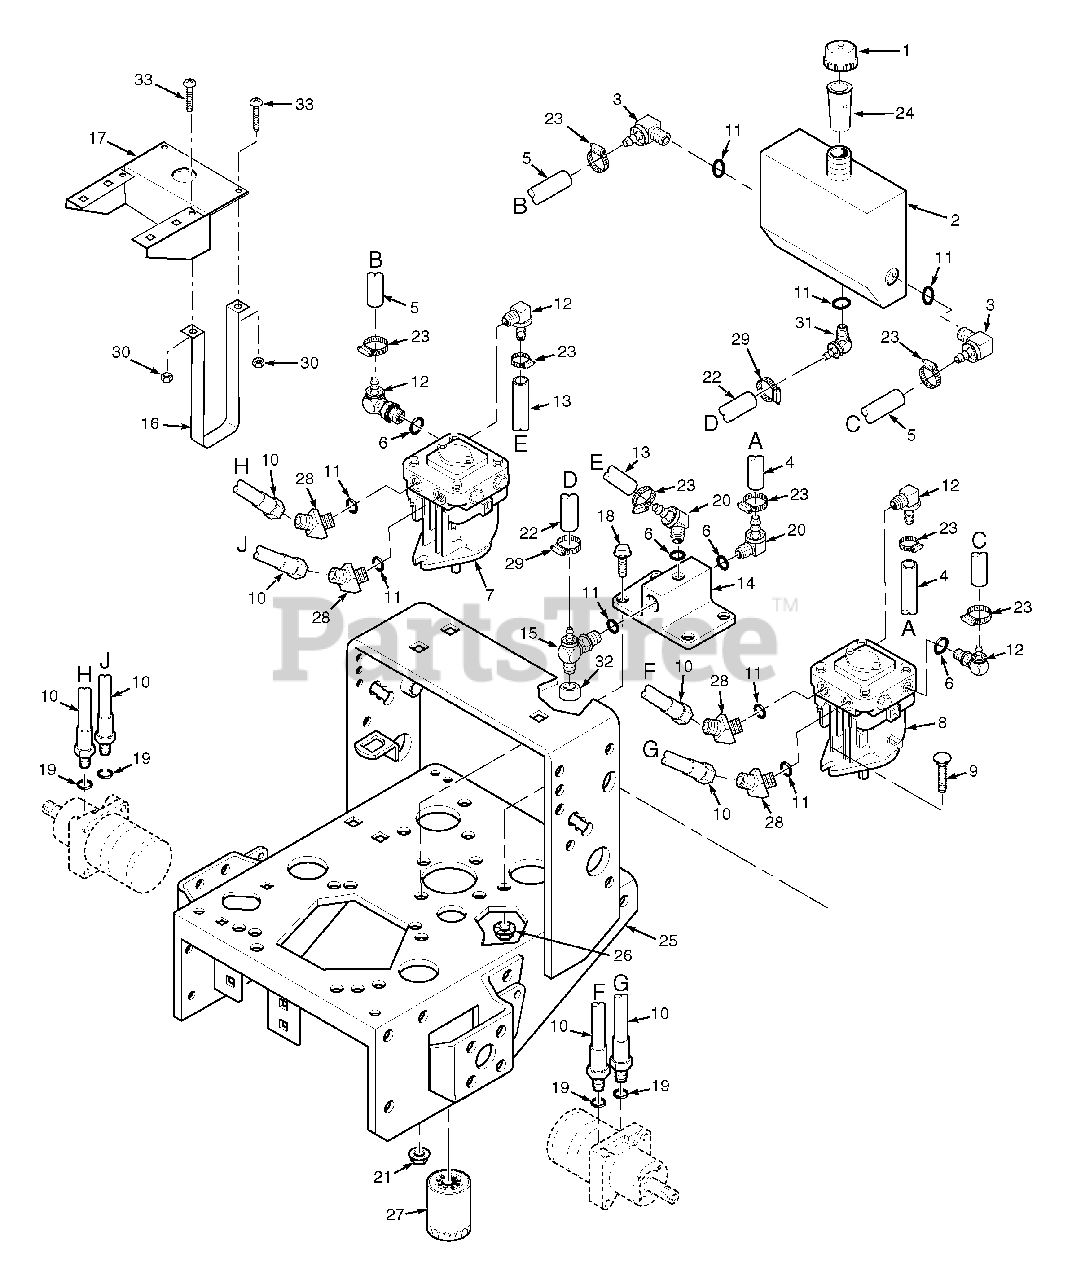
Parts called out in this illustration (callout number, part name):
1	Cap, Oil Reservoir
2	Oil Reservoir (With Fittings)
3	Elbow, 9/16 O-Ring x 3/8 Hose
4	Hose, 3/8" ID - 10-1/4" Long
5	Hose, 3/8" ID - 7" Long
6	O-Ring
7	Pump, PG-1JQQ-DY1X-XXXX (R.H.)
8	Pump, PG-1GQQ-DY1X-XXXX (L.H.)
9	Bolt, Carriage, 3/8-16 x 1.25"
10	Hose, Pump to Wheel Motor
11	O-Ring
12	Elbow, 7/16-20 O-Ring x 3/8 Hose
13	Hose, 3/8" ID - 8-1/4" Long
14	Oil Filter Base
15	Tee, 3/8 O-Ring x JIC x 1/2 Hose
16	Strap, Hydraulic Tank
17	Bracket, Hydraulic Tank
18	Capscrew, 5/16-18 x .75" Serr. Flange
19	O-Ring
20	Elbow, 9/16 O-Ring x 3/8 Hose
21	Nut, 5/16-18 Serr. Flange
22	Hose, Formed 1/2" ID
23	Clamp, .69 max dia.
24	Tube, Filler Neck
25	Engine Deck (16" Wide) W/Decals - Small Frame
26	Nut, 3/8-16 Serr. Flange
27	Oil Filter
28	Elbow, 45 Deg.-3/4-16 JIC Male x Male 3/4-16 O-Ring
29	Clamp, .87 max di.
30	Nut, 1/4-20
31	Elbow, 3/4-16 O-Ring x 1/2 Hose
32	Cap, 3/4-16
33	Screw, 1/4-20 x 2.0" Round Head Phillips
